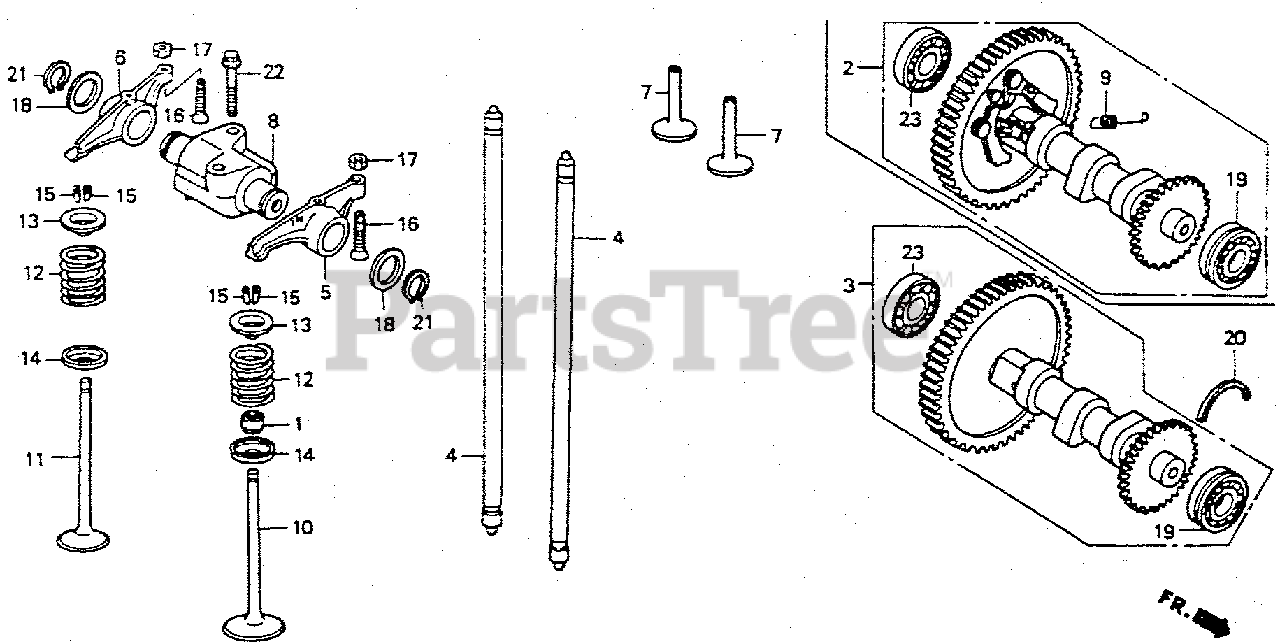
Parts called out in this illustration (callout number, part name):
1	SEAL A, VALVE STEM (ARAI)
2	CAMSHAFT ASSY. (USA)
4	ROD, PUSH
5	ARM, IN. VALVE ROCKER
6	ARM, EX. VALVE ROCKER
7	LIFTER, VALVE
8	SHAFT, ROCKER ARM
9	SPRING, WEIGHT RETURN
10	VALVE, IN.
11	VALVE, EX.
12	SPRING, VALVE
13	RETAINER, VALVE SPRING
14	SEAT, VALVE SPRING
15	COTTER, VALVE
16	SCREW, TAPPET ADJ.
17	NUT, TAPPET ADJ.
18	WASHER, THRUST (16MM)
19	BEARING A, SPECIAL BALL (6204) (NTN CORP.)
20	SET-RING (470)
21	CIRCLIP (OUTER) (16MM)
22	BOLT, FLANGE (6X35)
23	BEARING, RADIAL BALL (6204)
